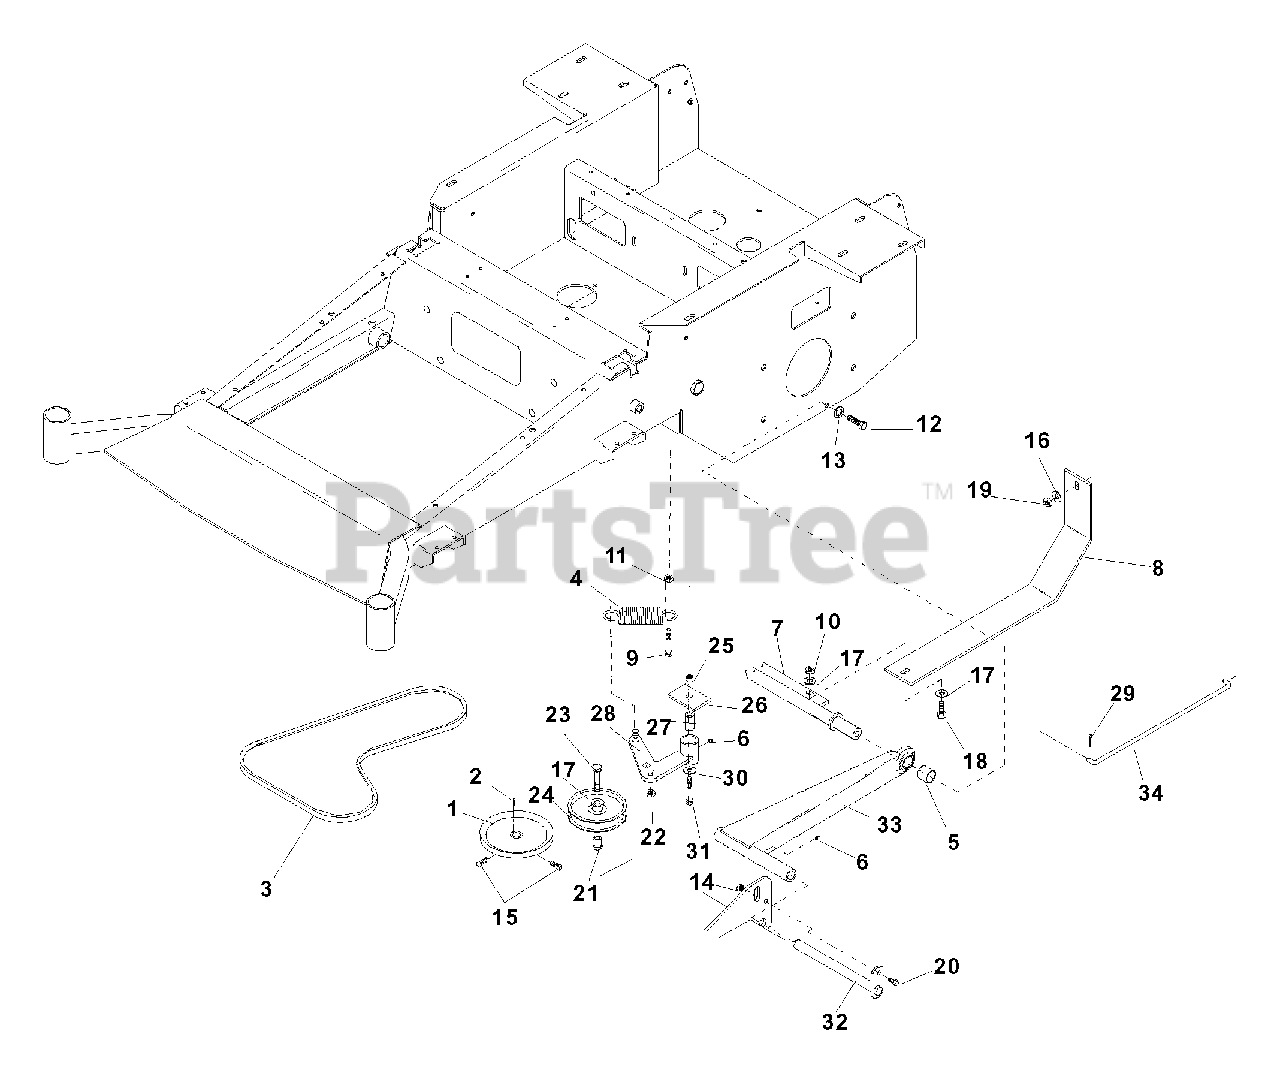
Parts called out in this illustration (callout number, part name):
2	KEY, 5MM SQ x 25MM
3	PUMP BELT
5	STRUT SPACER
6	ZERK
7	CROSS SHAFT
8	SKID PLATE
9	HCS, 3/8 C x 1 1/2
10	NUT, 3/8C, NYLOC
11	NUT, 3/8 C, WHIZ
12	HCS, 7/16 C x 1, GR8
13	LOCKWASHER, 7/16
14	NUT, 5/16C, NYLOC
15	ROLL PIN, 5/16
16	WASHER, 5/16
17	WASHER, 3/8
18	HCS, 3/8 C x 1
19	NUT, 5/16C, CENTERLOCK
20	HCS, 5/16C x 1
21	IDLER FLANGE BUSHING
22	NUT, 3/8C, CENTERLOCK
23	HCS, 3/8 C x 1 3/4
24	IDLER PULLEY
25	NUT, 1/2C, NYLOC
26	SUPPORT PLATE
27	PIVOT BUSHING
28	IDLER ARM
29	PIN, COTTER, 1/8 x 3/4
30	WASHER, 1/2
31	HCS, 1/2C x 3 1/4, GR5
32	STRUT PIN, 52"/61" DECK
32	STRUT PIN, 72" DECK
33	STRUT, 52"/61" DECK
33	STRUT, 72" DECK
